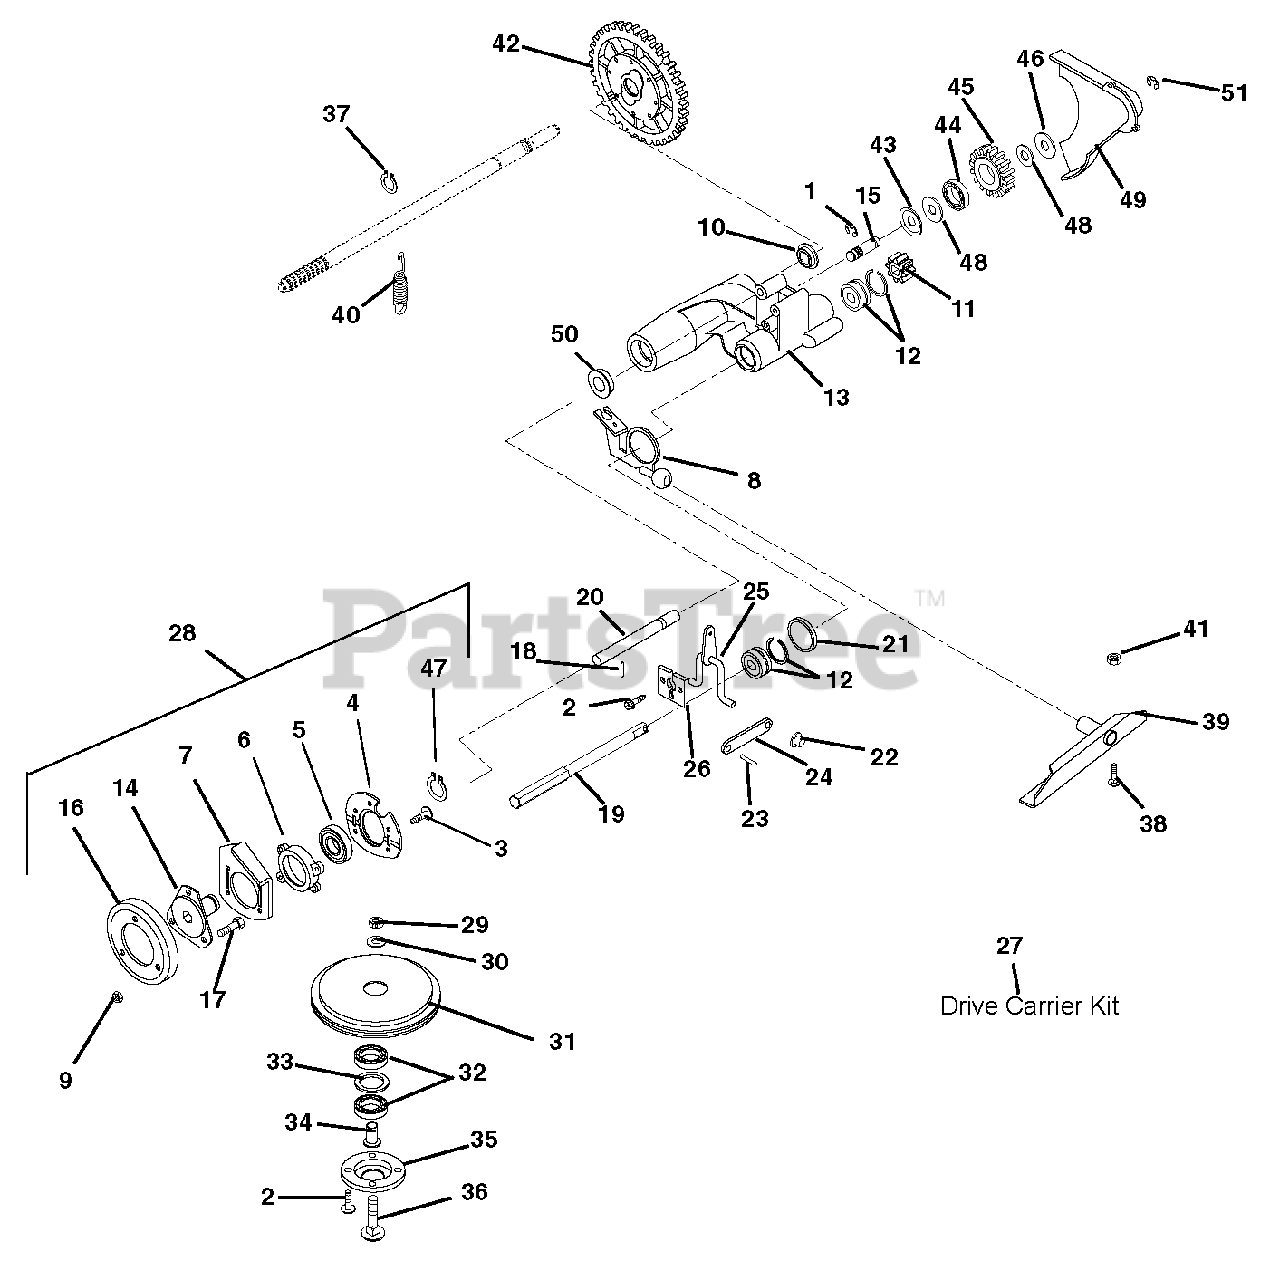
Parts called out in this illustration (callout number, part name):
1	Ring, Retaining External .438 x .035
2	Screw, Tapping 12-24 x .50 Hex Washer Head
3	Screw, Tapping 5 x 0.8 x 16MM
4	Bearing Retainer
5	Bearing Ball 1.00 x 2.00 x .56
6	Bearing Retainer
7	Bearing Plate
8	Drive Actuator Weldment
9	Nut, Locking Center .25-20
10	Bearing, Ball .625 x 1.38 x .44
11	Pinion, D-Shaft
12	Bearing, Ball .50 x 1.375 x .437
13	Drive Mount
14	Hub, Friction Wheel
15	Idler Shaft
16	Disc, Friction
17	Bolt, Hex .25-20 x .50 Grade 5
18	Pin, Roll .188 x .88
19	Shaft, Friction Disk
20	Rod, Guide
21	Washer, Flat Steel 1.390 x 2.00 x .020
22	Push Nut .25
23	Pin, Roll .125 x .50
24	Shift Link
25	Shift Arm Weldment
26	Retainer Plate
27	Kit, LM Drive Carrier (Includes Items 1 - 26)
28	Friction Wheel Assembly
29	Nut, Locking Center .31-18
30	Washer, Flat Steel .38 x .87 x .179
31	Friction Sheave
32	Bearing, Ball .625 x 1.375 x .43
33	Washer, Flat Steel 1.062 x 1.344 x .032
34	Spindle, Bearing
35	Bearing, Retainer
36	Bolt, Round Head Square Neck .31-18 x 1.75 Grade 5
37	Ring, Retaining External .579 x .930
38	Bolt, Round Head Square Short Neck .31-18 x .62
39	Pivot Channel Weldment
40	Spring, Tension .051 x .60 x 2.25
41	Nut, Locking-Top-Flange .31-18
42	Differential Assembly
43	Retainer
44	Bearing, Ball .50 x 1.38 x .437
45	Idler Gear
46	Washer, Flat Steel .531 x 1.00 x .063
47	Ring, Retaining External 1.00 x .042
48	Washer, Flat Steel .520 x .827 x .062
49	Gear Cover
50	Bearing, Ball .625 x 1.383 x .50
51	Ring, Retaining External .438 x .035
